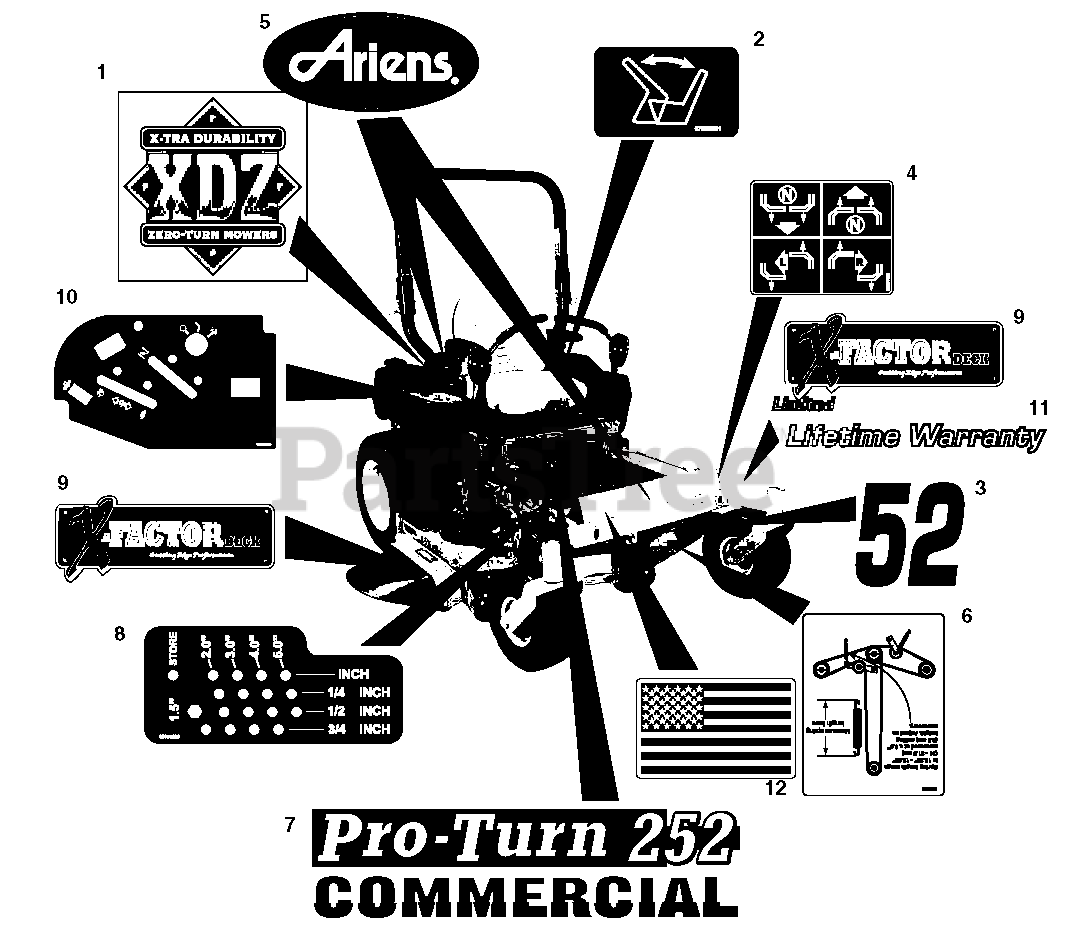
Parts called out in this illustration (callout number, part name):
1	Decal, XDZ
2	Decal, Seat Release
3	Decal, 52
4	Decal, Instructional- Steering
5	Decal, Ariens Oval
6	Decal, Belt Routing
7	Decal, Pro-Turn 252
8	Decal, Height of Cut
9	Decal, X-Factor Deck
10	Decal, Control Panel
11	Decal, Limited Lifetime Warranty
12	Decal, American Flag
